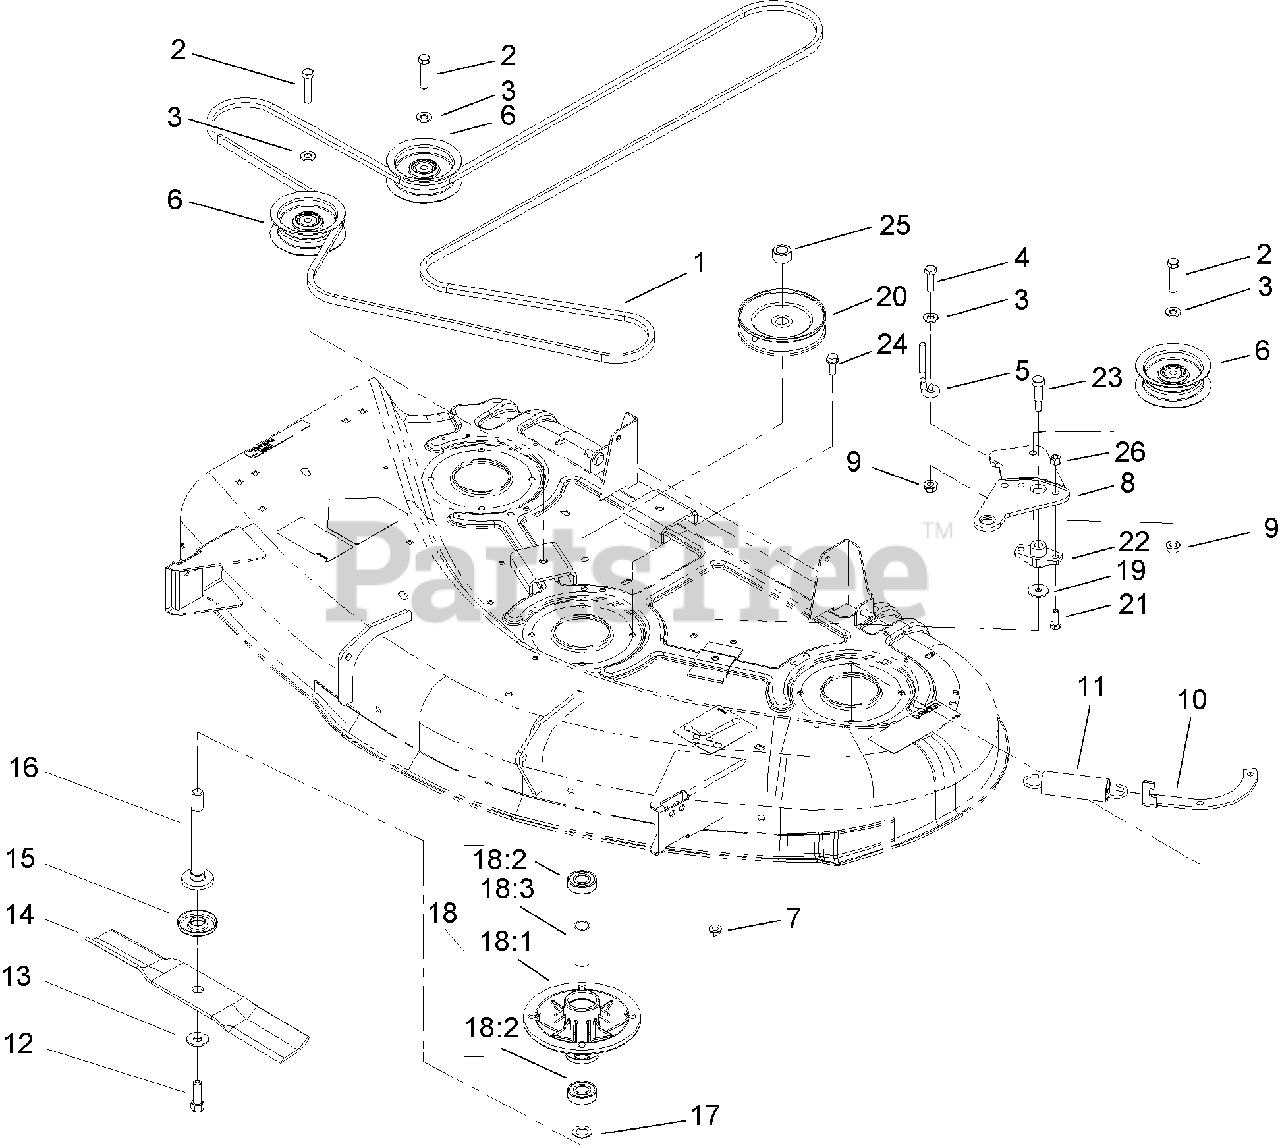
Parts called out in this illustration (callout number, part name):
2	SCREW-HH
3	WASHER-FLAT
4	SCREW-HH
5	GUIDE-IDLER, BELT
6	PULLEY-IDLER, FLAT
10	BRACKET-SPRING
11	SPRING-EXTENSION
12	SCREW-BLADE
13	WASHER-BELLEVILLE
15	SHIELD-BEARING
16	SHAFT-SPINDLE
18	Spindle ASM
18:1	HOUSING-SPINDLE
18:2	BEARING-BALL
18:3	SPACER-BEARING
19	WASHER-PIVOT
20	PULLEY ASM
21	SCREW-HH
22	BUSHING-ARM, IDLER
23	BOLT-SHOULDER
24	SCREW-TAPTITE
25	NUT-HEX
26	NUT-LOCK, NI
